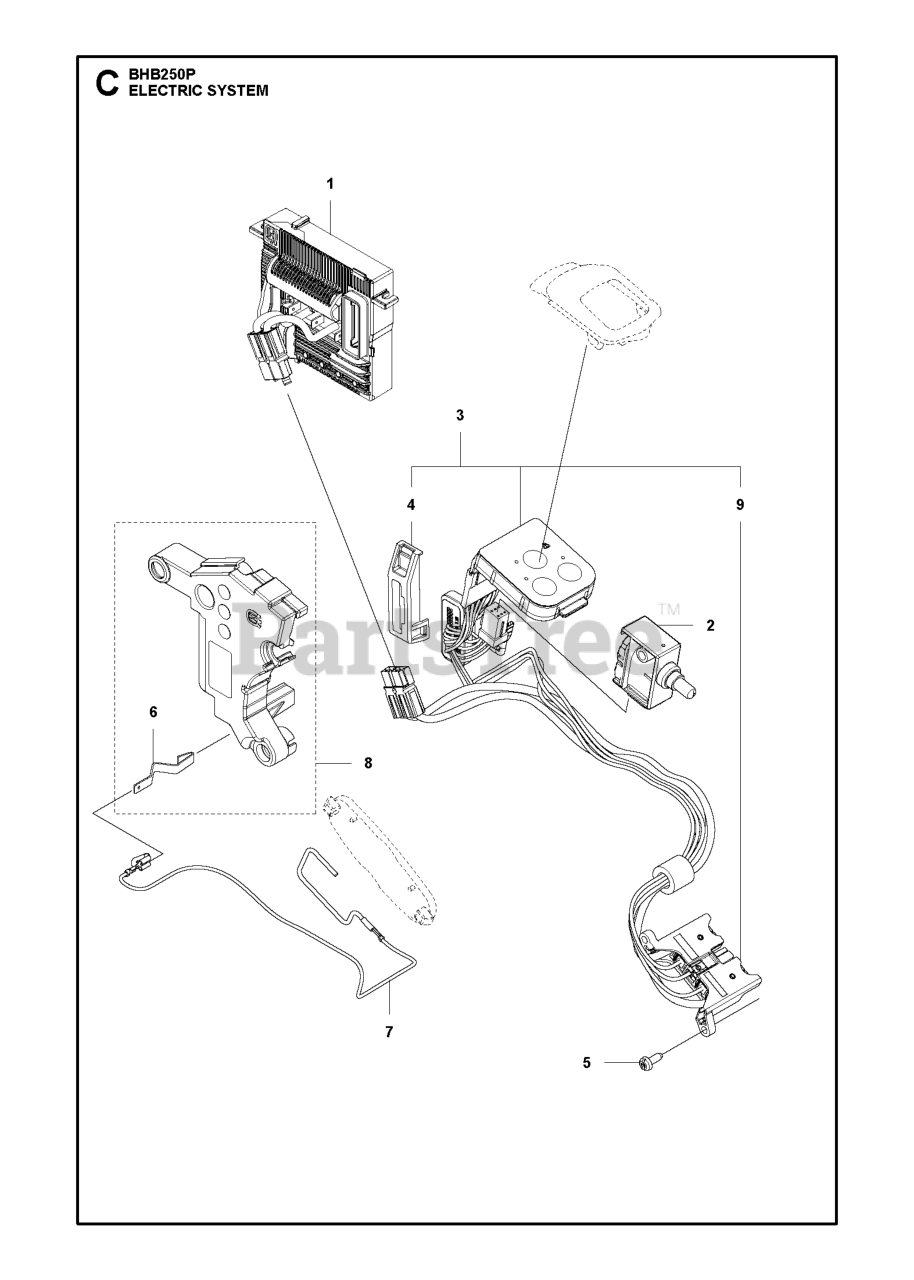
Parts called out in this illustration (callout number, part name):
1	CONTROL UNIT BLDC MID SPEC, GE
2	TRIGGER SWITCH IPX4
3	WIRING ASSY BLOWER MAIN
5	SCREW CCRPANT
7	WIRING ASSY
8	KIT COVER ELECTRONICS
9	CONNECTOR BATTERY
